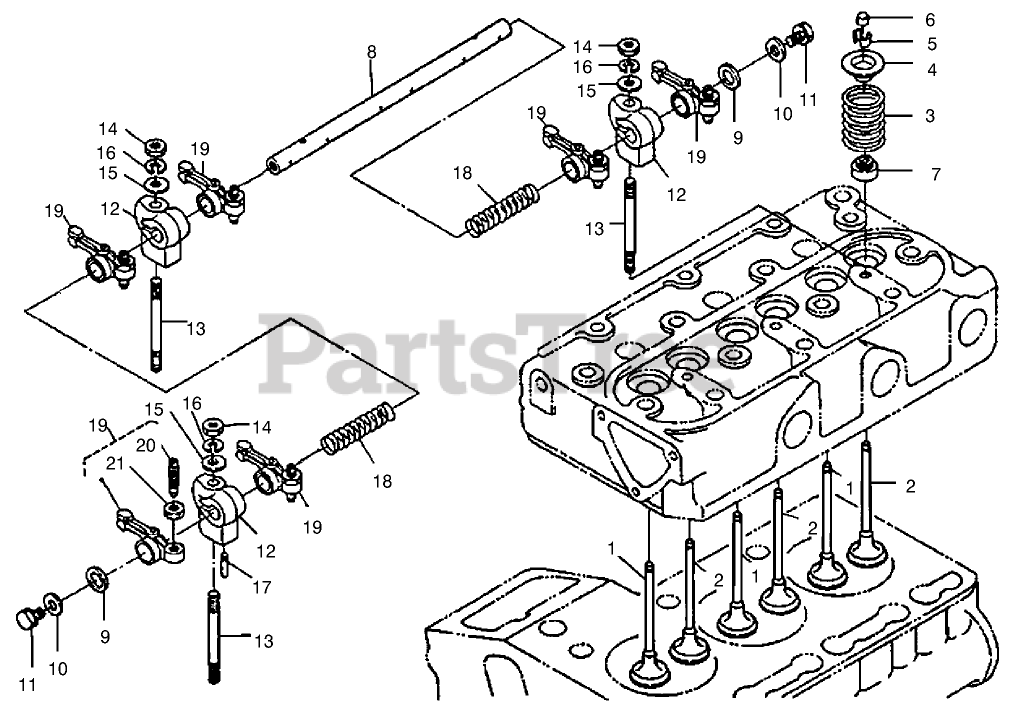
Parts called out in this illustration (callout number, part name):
1	VALVE-INLET
2	VALVE-EXHAUST
3	SPRING-VALVE
4	RETAINER-SPRING, VALVE
5	COLLET-SPRING, VALVE
6	CAP-VALVE
7	SEAL-STEM, VALVE
8	SHAFT-ARM, ROCKER
9	WASHER
10	WASHER-PLAIN
12	BRACKET-ARM, ROCKER
15	WASHER-PLAIN
16	WASHER-SPRING
17	PIN-SPRING
18	SPRING-ARM, ROCKER
19	ROCKER ARM ASM
20	SCREW-ADJUSTING
